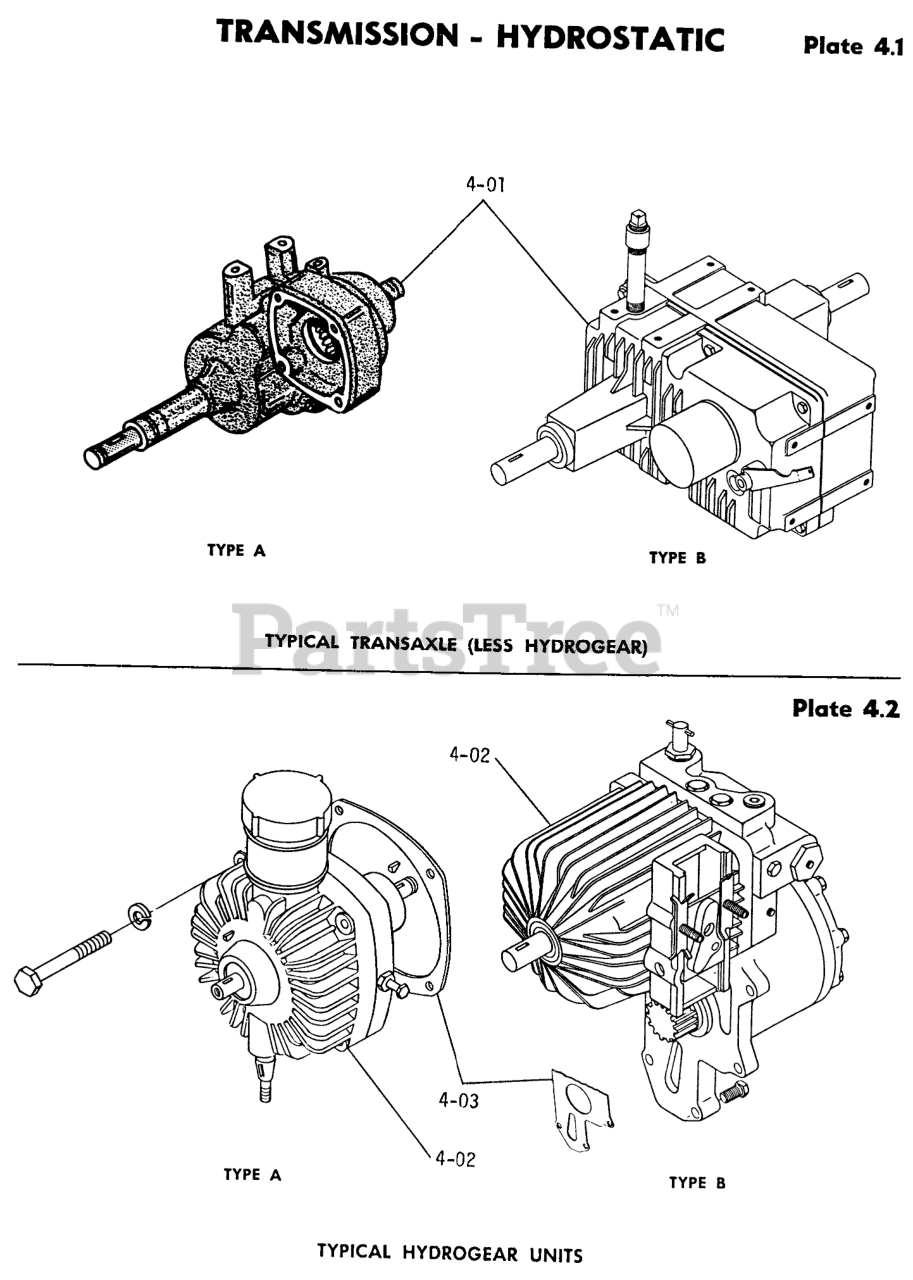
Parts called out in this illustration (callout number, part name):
4-01	Assy.-Transaxle-Tyne B-Note 2
4-01	SEE BULL 189/122
4-02	SRV BULLT 437B
4-02	Assy.-Hydrogear-Type B-Note 3
4-02	SER BULLT 437B
4-02	Hydro-Gear Unit (Rebuilt)
4-02	Bolt Hex 3/8-16 x 3
4-02	Lockwasher
4-02	Bolt, 3/8-16 x 1
